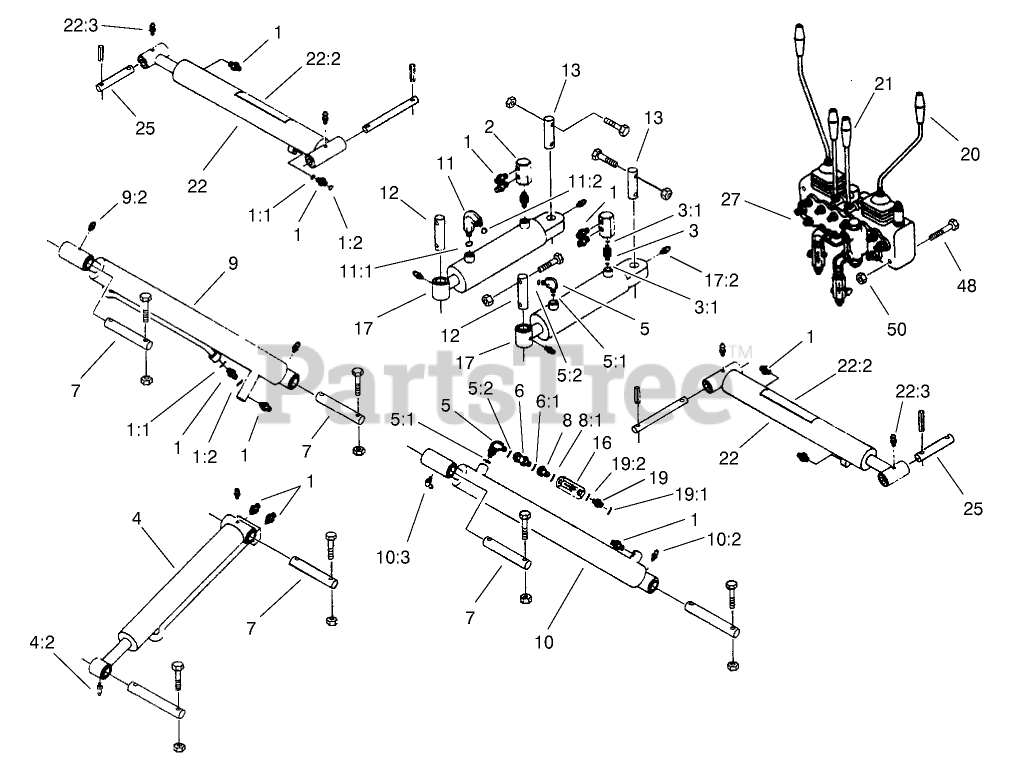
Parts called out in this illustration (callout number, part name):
1	FITTING-STRAIGHT
1:1	O-RING
1:2	O-RING
2	FITTING-HEX
3	FITTING
3:1	O-RING
4	CYLINDER-HYD, BUCKET
4:1	SEAL KIT
4:2	FITTING-GREASE
5	FITTING-90 DEG
5:1	O-RING
5:2	O-RING
6	FITTING-SWIVEL, STRAIGHT
6:1	O-RING
7	PIN-BOOM
8	FITTING-REDUCER
8:1	O-RING
9	CYLINDER-HYD, CROWD ARM
9:1	SEAL KIT
9:2	FITTING-GREASE
10	CYLINDER-HYD, BOOM
10:1	SEAL KIT
10:2	FITTING-GREASE
10:3	FITTING-GREASE
11	FITTING-90 DEG
11:1	O-RING
11:2	O-Ring
12	PIN-SWIVEL, FRONT
13	PIN-SWIVEL, REAR
16	VALVE-CONTROL, FLOW
17	CYLINDER-HYD, SWING
17:1	SEAL KIT
17:2	FITTING-GREASE
19	FITTING-STRAIGHT
19:1	O-Ring
19:2	O-RING
20	BENT HANDLE ASM
21	STRAIGHT HANDLE ASM
22	STABILIZER CYLINDER ASM
22:1	SEAL KIT
22:2	DECAL-WARNING
22:3	FITTING-GREASE
25	PIN-CYLINDER, STABILIZER
27	VALVE ASM
48	SCREW-HH
50	NUT-LOCK, NI
